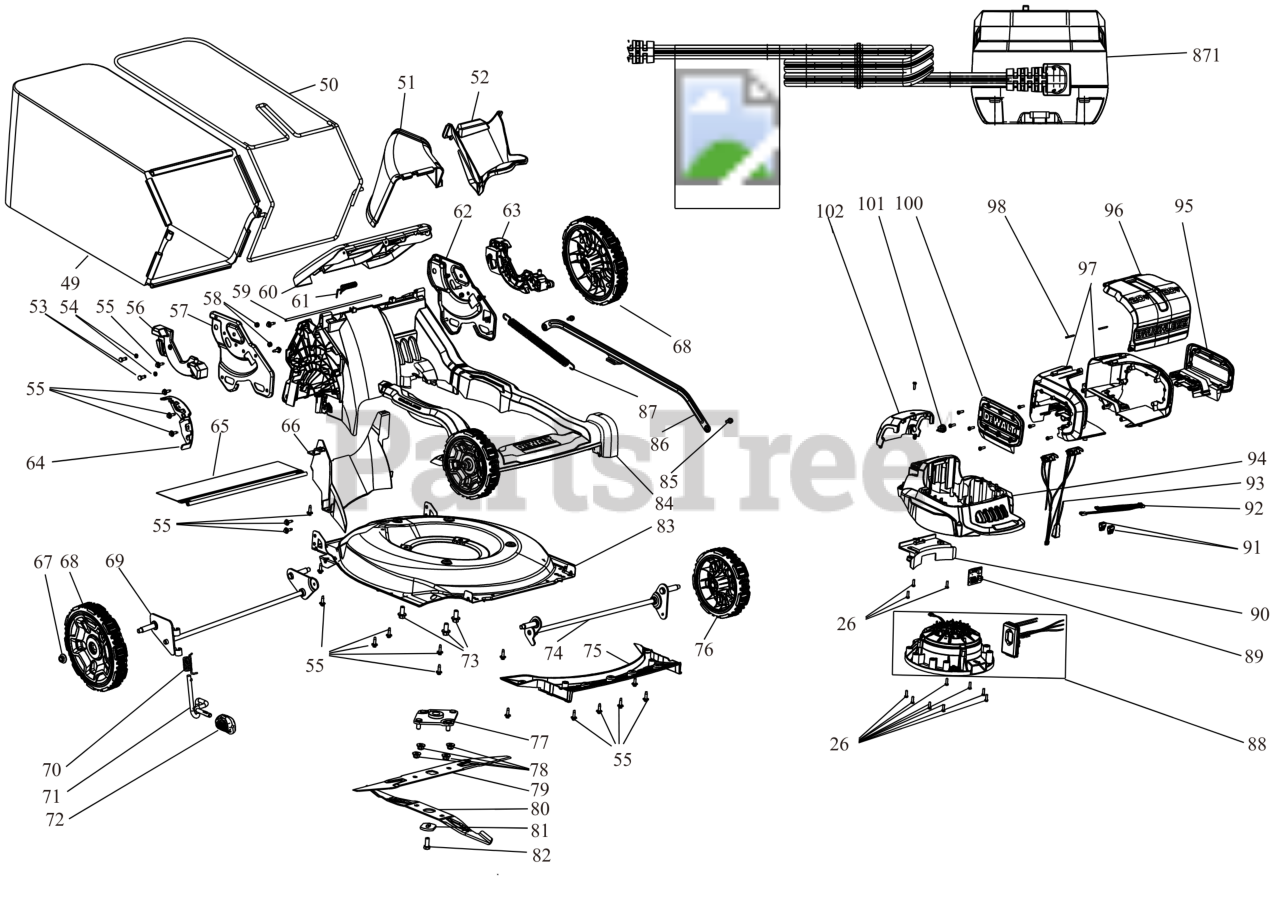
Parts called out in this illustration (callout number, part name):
1	BUTTON
2	SCREW
3	SPRING
5	COVER
6	CONTROL
8	BUTTOM
9	HANDLE SA
10	SWITCH
11	WIRE HARNESS
13	SCREW M6X45-T30-THD FRM
14	COVER
16	SWITCH COVER
17	CATCH
19	SPRING TORSION
20	WIRE HARNESS
21	STRIP
22	SLEEVE
23	TUBE UPPER
25	TUBE LOWER
26	SCREW M4.55X16 T20-PLAS THD FRM
27	SLEEVE
29	WASHER
30	SCREW
33	SPRING
35	SPRING
36	SPRING
37	COVER
40	SPRING
43	HOLDER
44	HARNESS
45	COVER
46	BUTTON
47	COVER
49	GRASSBAG
50	FRAME
51	CHUTE
54	SPACER
55	SCREW 1/4-10 x .750
56	SUPPORT
57	BRACKET
58	LOCK-NUT
61	SPRING
62	BRACKET
63	SUPPORT
64	BRACKET
65	SHIELD
66	INSERT
67	FLANGE LOCK NUT
68	WHEEL
69	AXLE REAR
70	SPRING
74	AXLE FRONT
76	WHEELS
77	PLATE
79	BLADE MOUNT
80	BLADE MOUNT
81	WASHER
83	PLATE
87	SPRING
88	MOTOR SA
89	PCB SA
90	BAFFLE
91	CONNECTOR
92	HARNESS
93	WIRE HARNESS
94	COVER
95	PLATE SA
97	HOUSING SA
100	COVER SA
101	BUSHING
102	COVER
103	SA HANDLE PNL KIT PUSH-BLACK
104	LABEL
866	20V BATTERY MAX XR 10AH DCB210
871	CHARGER
